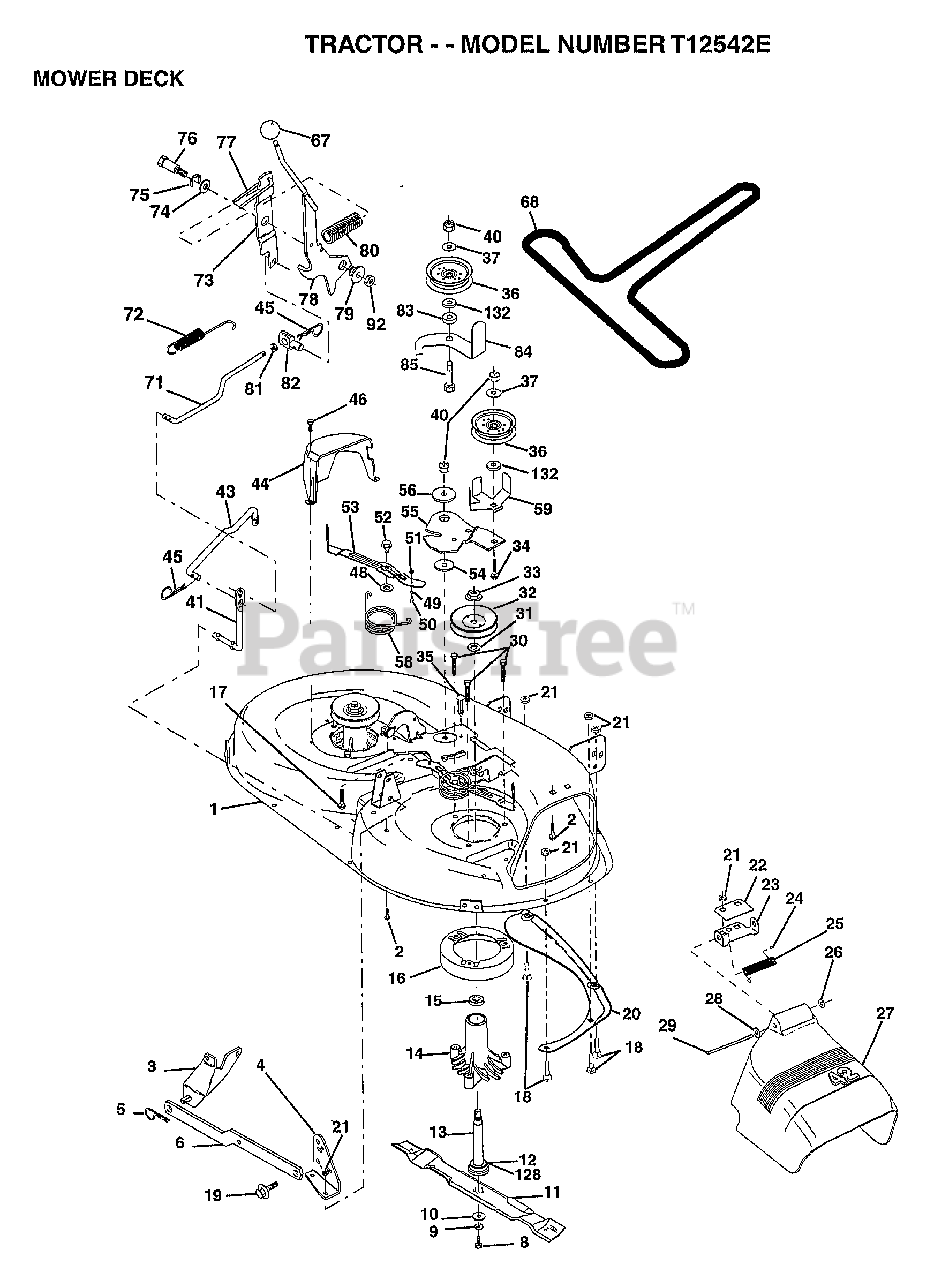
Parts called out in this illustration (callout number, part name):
1	DECK.WELD.42.
2	BOLT
3	BRKT ASM SWAY BAR
4	BRKT DECK SW BAR
8	BLADE BOLT
10	WASHER.HARD.BLADE
11	"BLADE.42"" HIPERF"
12	BEARING.BALL
14	HSG ASM MANDREL
15	BEARING
16	STRIPPER RND MWR
17	BOLT RDHD 3/8-16
18	BOLT
19	BOLT SHD 5/16-18
22	STIFFENER BRKT
23	DEFLECTOR BRKT
24	CAP-SLEEVE LT
25	SPRING TORSION
26	NUT PUSH M
27	DEFLECTOR.SHIELD
28	WASHER
29	HINGE ROD
31	WASHER
32	PULLEY.MANDREL.42
34	BOLT
35	XMAS TREE FASTNER
36	FLAT IDLER PULLEY
37	WASHER
41	PIVOT ROD
43	ROD CLUTCH W/NIBS
44	GUARD MAND LH BLK
45	RETAINER M
46	SCREW.1/4-20X5/8
48	HARD SMALL WASHER
49	ROLLER ASM-CAM
50	SHOULDER BOLT
51	LOCKNUT
52	BOLT.SHLD.5/16-18
54	HARDENED WASHER
55	ARM-IDLER
56	SPACER RETAINER
58	SPRING TORSN BRAK
59	GUARD IDLER TUV
68	BELT.V.T-PATH
71	ROD CLUTCH 38/42
72	RETURN SPRING
73	CLUTCH ARM SECOND
74	WASHER
75	RING
76	SHOULDER BOLT
77	SPRING KEEPER
78	LEVER ASM-CLUTCH
79	BUSHING
80	SPRING.CLUTCH.MWR
81	TRUNION ADJ
82	NUT
83	WASHER
84	"KEEPER-BELT,FIXED"
85	BOLT RDHD 3/8-16
92	NUT
128	WASHER.FELT.
132	WASHER GT
